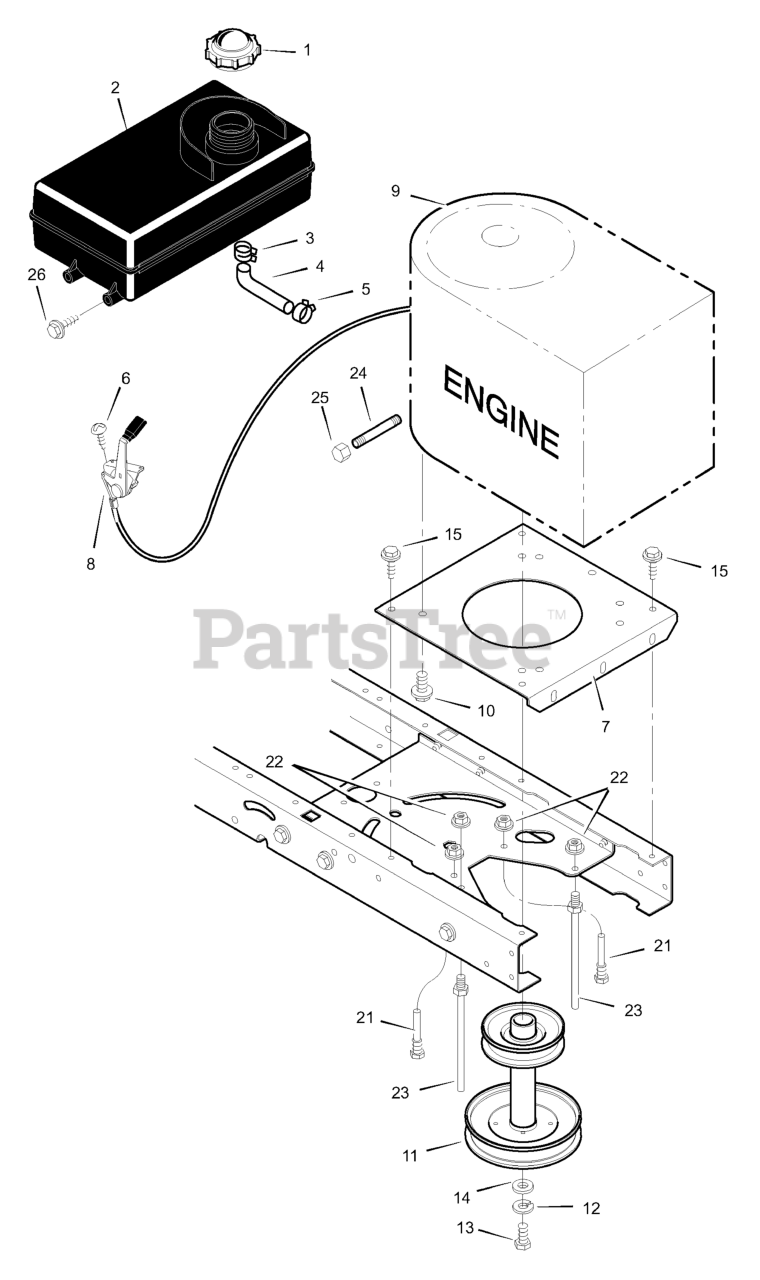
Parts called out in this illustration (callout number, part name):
1	Fuel Cap
2	TANK, Fuel 1.4 Gal.
3	Hose Clamp
4	Fuel Line
5	Hose Clamp
7	Plate, Engine
8	Throttle Control
9	Engine *
10	Bolt, Engine Mount
11	STACK PULLEY ASSEMBLY
12	Lockwasher
13	Bolt, Hex
21	Guide, Belt
22	Nut, Flange
23	Guide, Belt
24	Pipe, Oil Drain
25	Cap, Oil Drain
